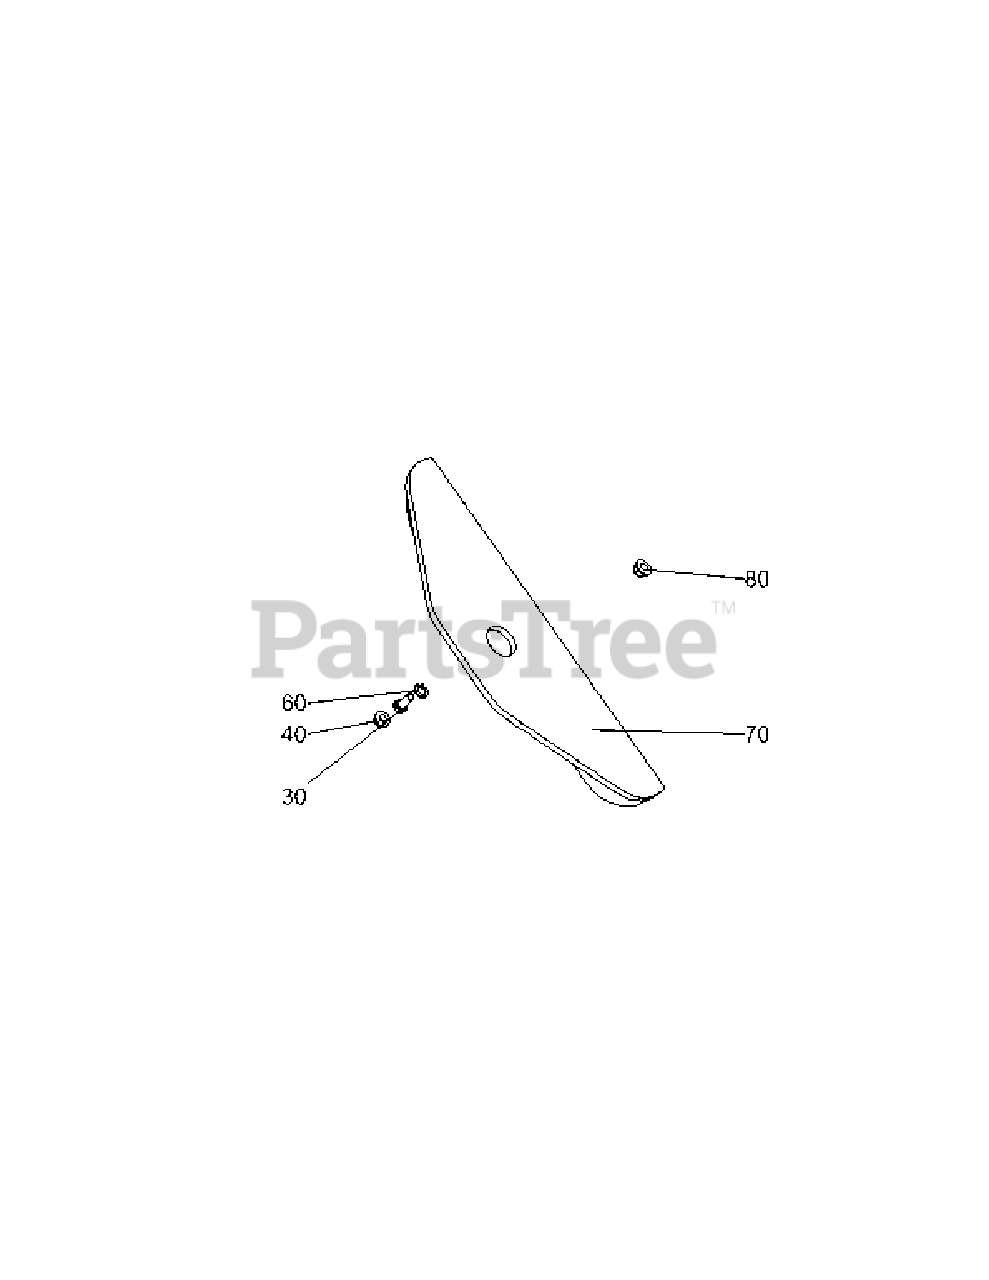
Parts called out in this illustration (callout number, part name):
30	Screw-Hex 5/16 X 3
40	Nut-Flange
60	Washer-Fl
80	Nut-Flglk 5/16-18
